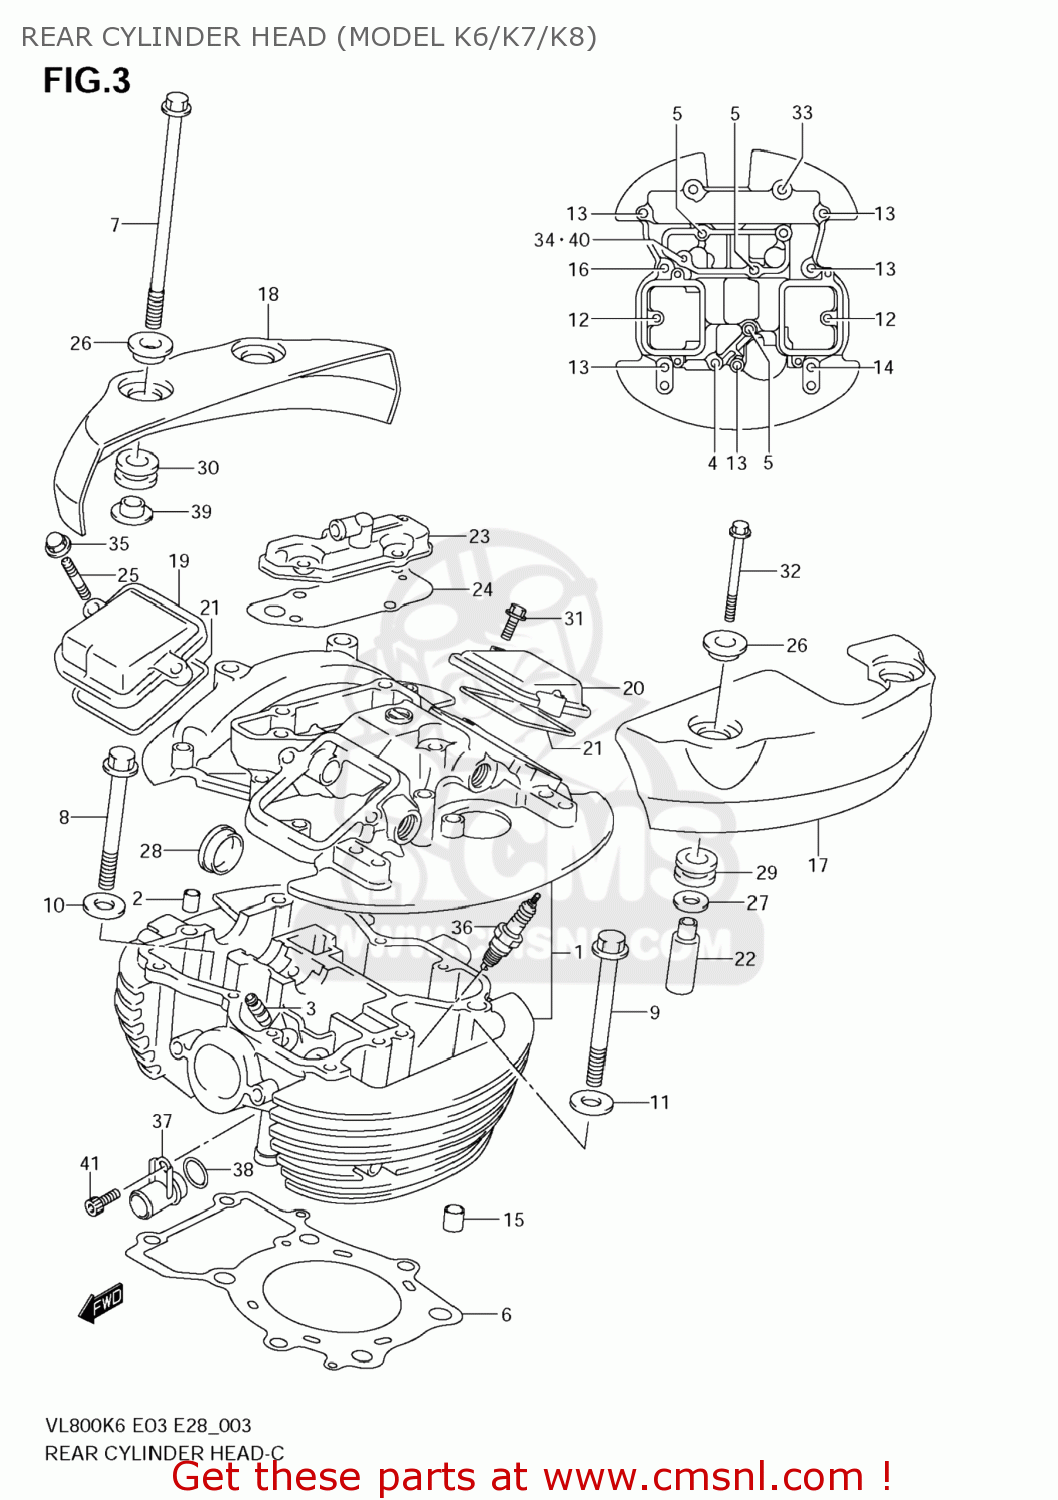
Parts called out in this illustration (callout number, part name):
1	HEAD ASSY,CYLINDER RR
2	PIN(8.4X11X14)
3	GUIDE,VALVE
4	BOLT(6X50)
5	BOLT(6X55)
6	GASKET,CYLINDER HEAD RR (NAS)
7	BOLT(8X250)
8	BOLT(10X155)
9	BOLT(10X165)
10	WASHER(10.5X22X2.3)
11	WASHER(10.5X22X2.3)
12	BOLT
13	BOLT
14	BOLT
15	PIN
16	BOLT
17	CAP,CYLINDER HEAD COVER RR,L
18	CAP,CYLINDER HEAD COVER RR
19	CAP,INSPECTION INTAKE
20	CAP,INSPECTION EXHAUST
21	GASKET,INSPECTION CAP (NAS)
22	SPACER,CYL HEAD COVER CAP NO.2
23	COVER,BREATHER
24	GASKET,BREATHER COVER (NAS)
25	BOLT,STUD
26	WASHER(6.5X18X1.6)
27	WASHER(9.5X20X1)
28	PLUG(OD:30)
29	CUSHION
30	CUSHION
31	BOLT
32	BOLT
33	BOLT
34	BOLT
35	NUT
36	SPARK PLUG X22E
37	UNION,CYL HEAD JOINT
38	O RING(D:2.4,ID:15.8)
39	BUSH
40	GASKET(5.8X13X1.2) (NAS)
41	BOLT
